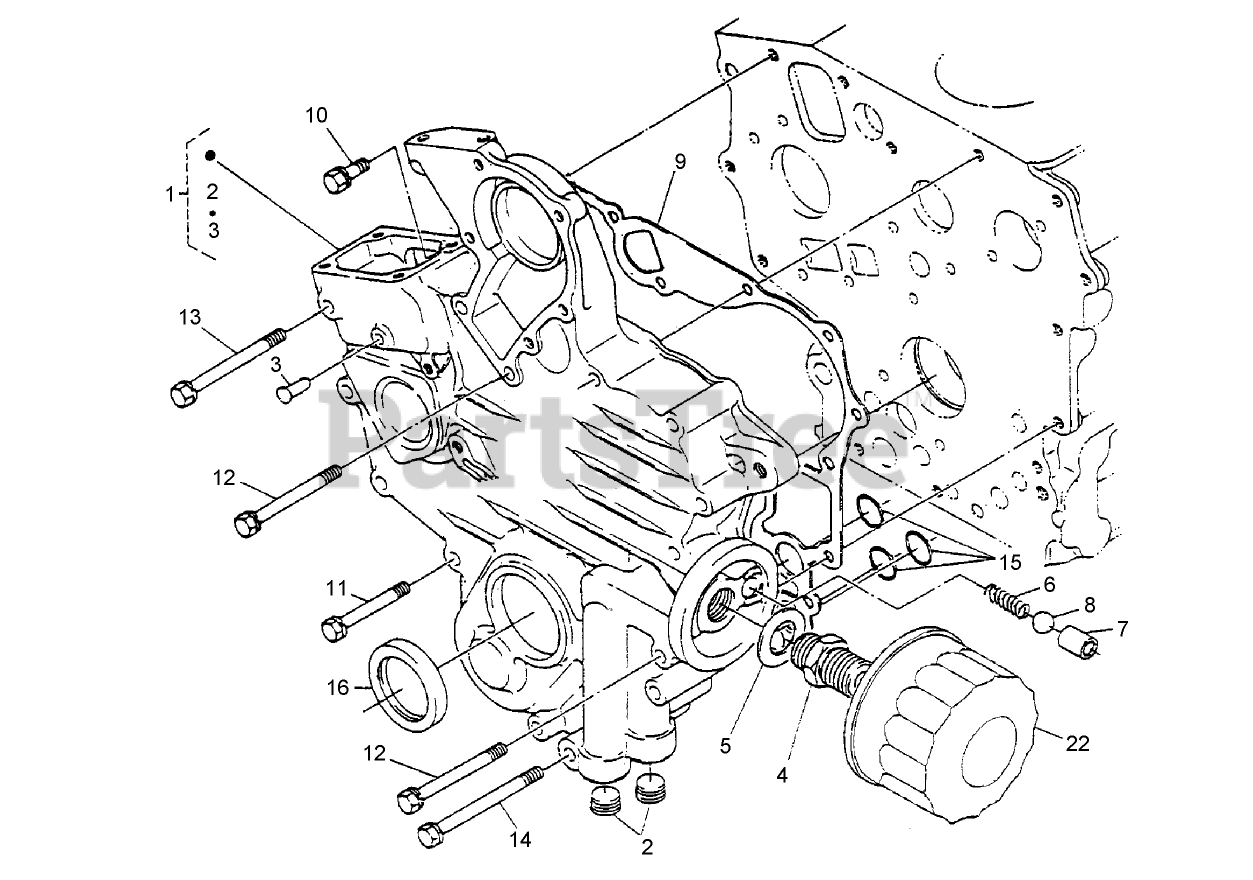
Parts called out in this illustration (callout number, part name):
1	GEAR CASE ASM
3	PIN-SPRING, START
4	JOINT-PIPE
5	WASHER-PLAIN
6	SPRING
7	SEAT-VALVE
9	GASKET-CASE, GEAR
15	O-RING
16	SEAL-OIL
22	CARTRIDGE-FILTER, OIL
